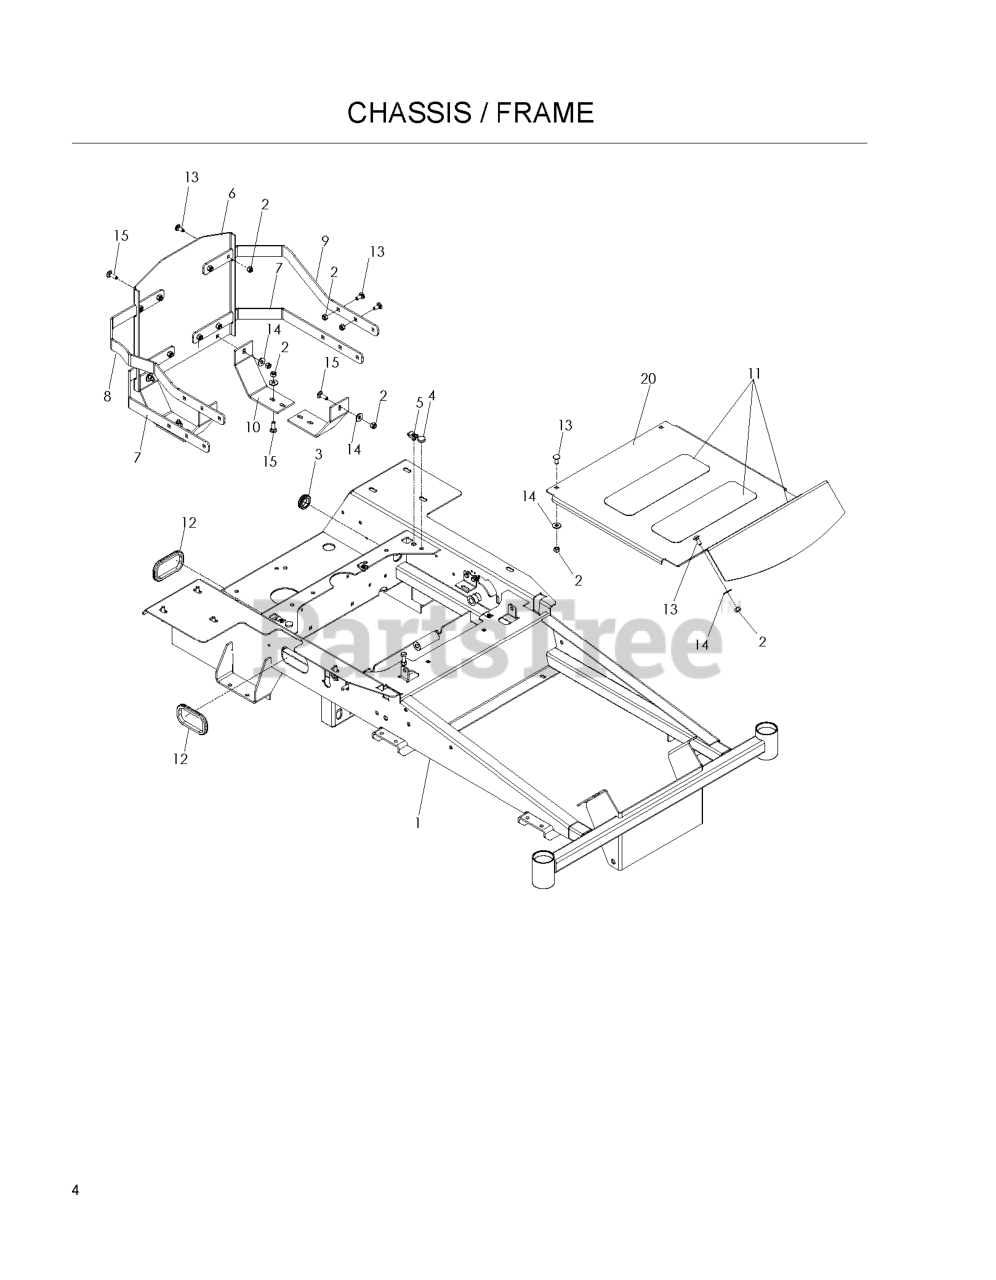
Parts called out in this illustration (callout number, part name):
1	FRAME W/DECALS
1	FRAME W/DECALS #
3	RUBBER GROMMET
4	GROMMET, BUMPER
5	U-CLIP 5/16-18 NUT RETAINER
6	ENGINE GUARD
7	REAR GUARD STRAP, LOWER
8	REAR GUARD STRAP, UPPER RIGHT
9	REAR GUARD STRAP, UPPER LEFT
10	SKID PLATE
11	ANTI-SKID PAD
13	BOLT 5/16C X 3/4" CARRIAGE
14	WASHER 5/16 FLAT
15	RHSNB 5/16C X 1
